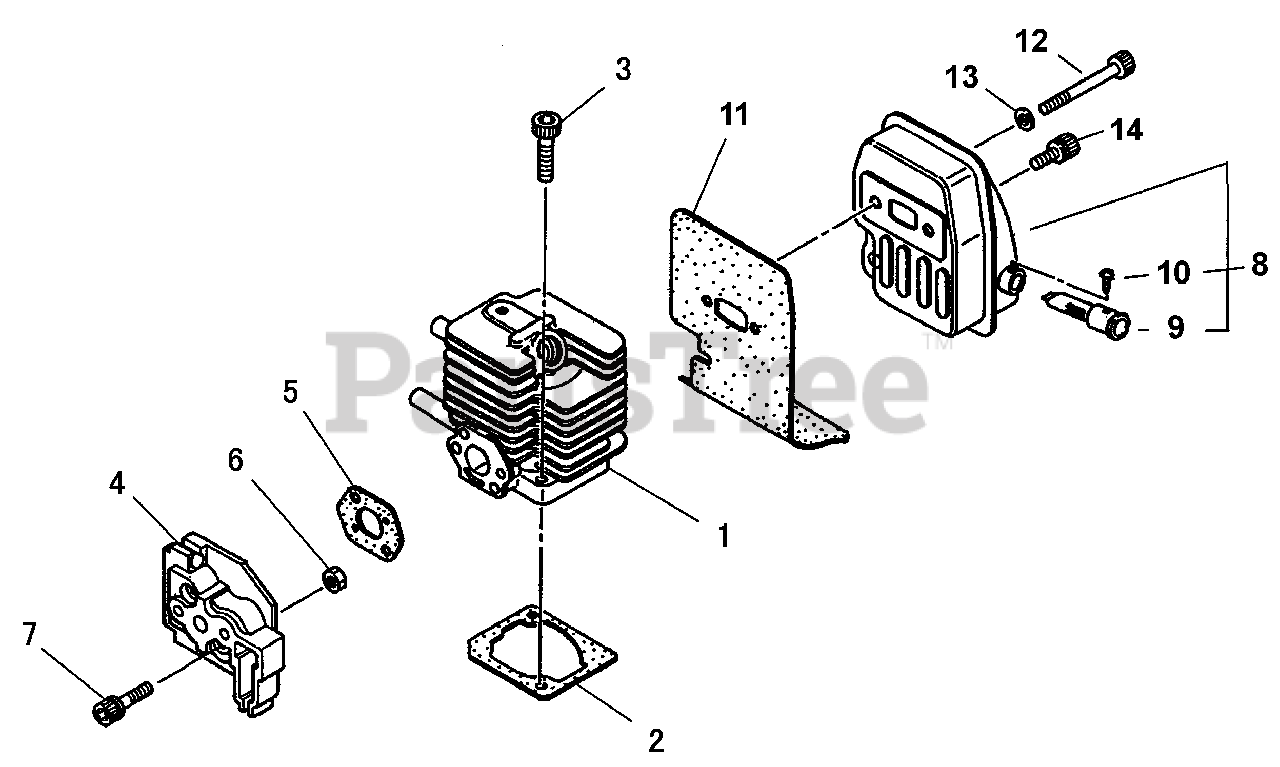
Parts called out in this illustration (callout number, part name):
1	CYLINDER
2	GASKET, CYLINDER
3	SCREW - 5X25
4	INSULATOR, INTAKE
5	GASKET, INTAKE
6	NUT - 5X6.3
7	SCREW - 5X30
8	MUFFLER ASSY
9	SCREEN, SPARK ARRESTOR
10	SCREW - 3X6
11	SHIELD, EXHAUST
12	SCREW - 5X50
13	WASHER - 5
14	SCREW - 5X12
